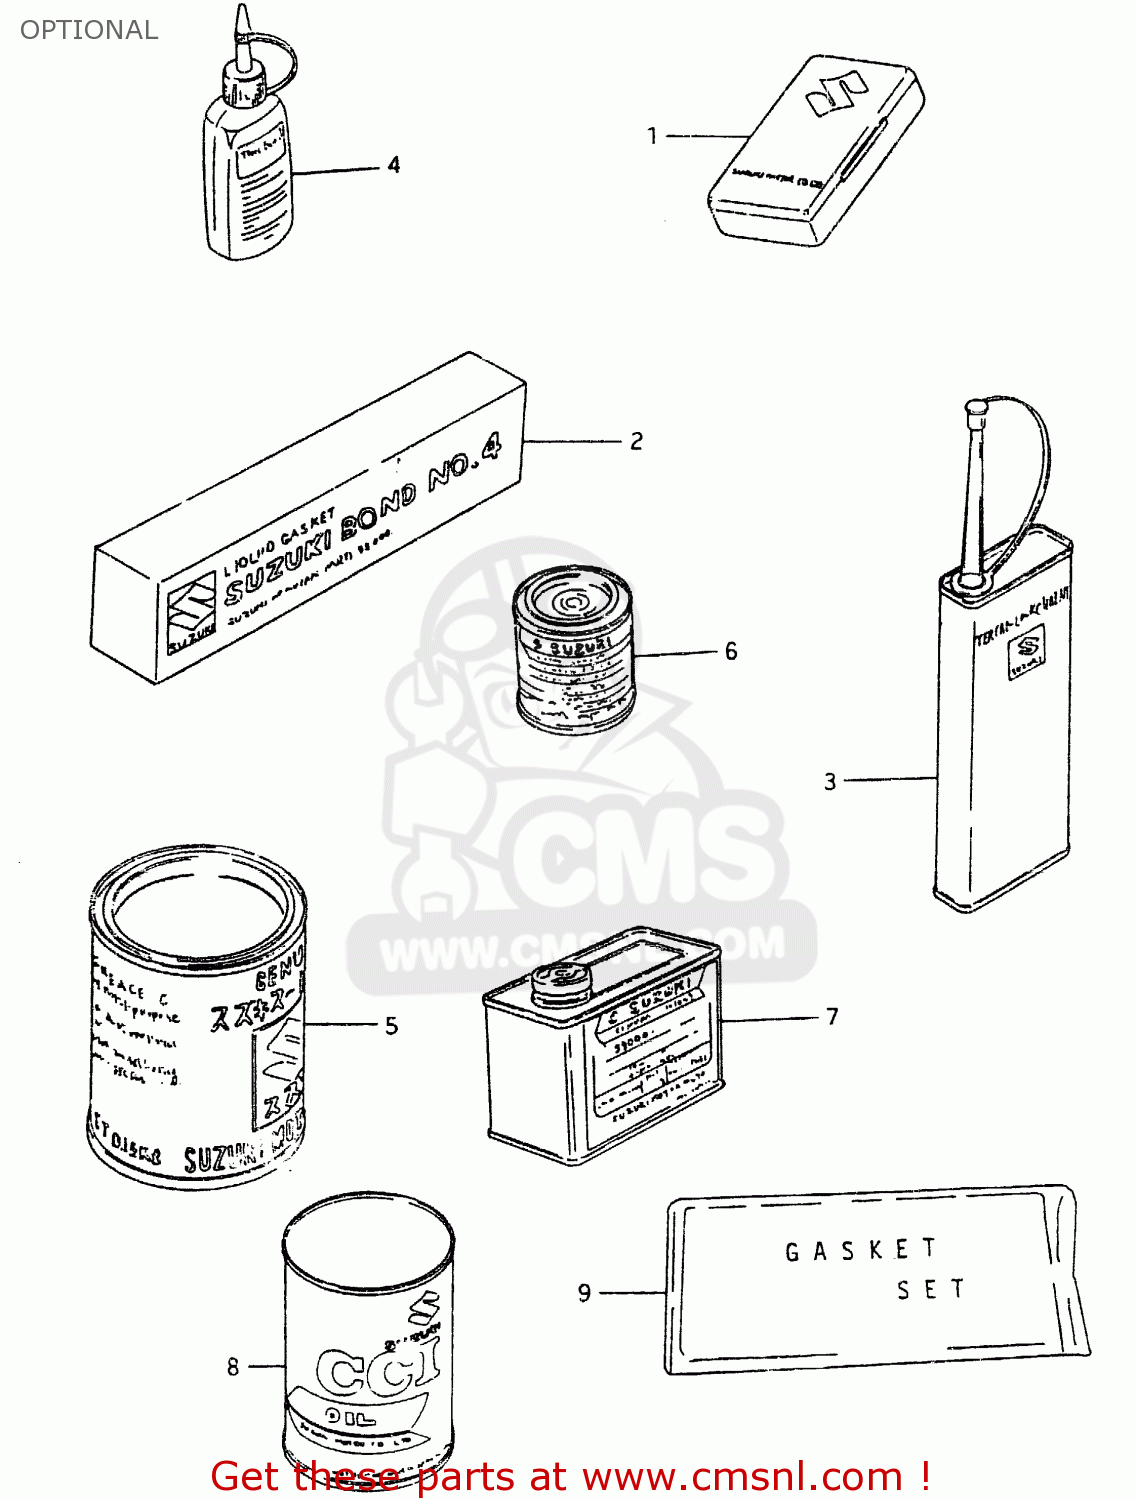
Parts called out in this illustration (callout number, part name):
1	TUBE REPARING TOOL
2	BOND 1104
3	THREAD LOCK NO.1401 CLEAR 200G
4	THREAD LOCK NO.1342
5	GREASE(C)EP2 LITHIUM 150G
6	PAINT,BLACK
7	PAINT (BLACK)
8	CCI OIL
9	GASKET SET
